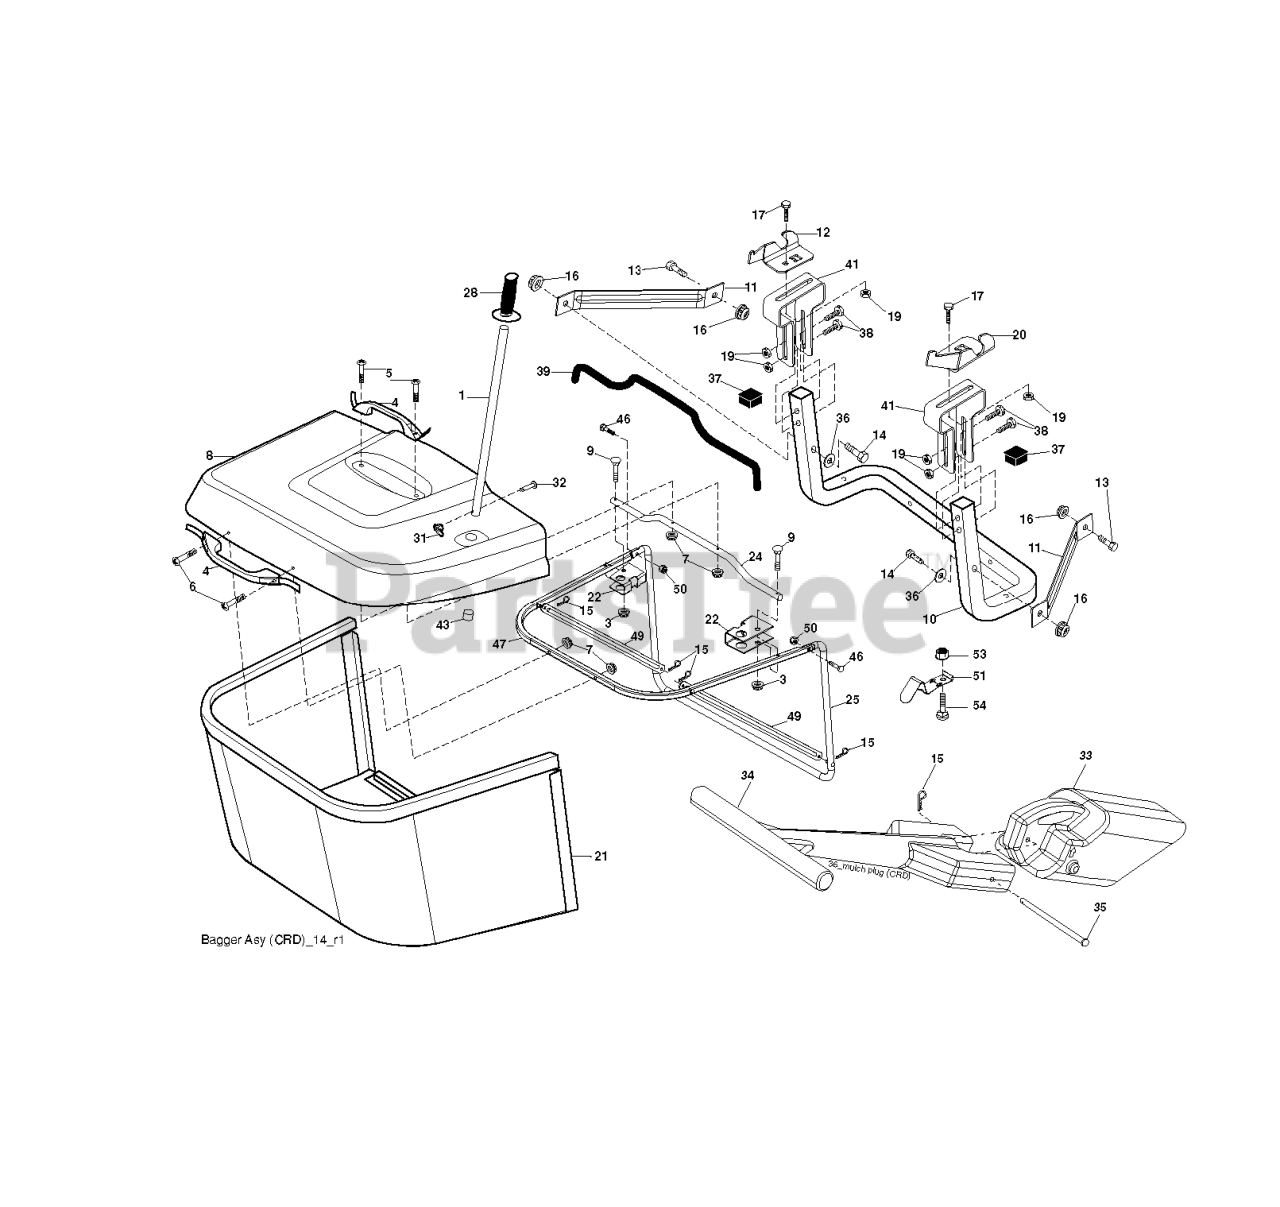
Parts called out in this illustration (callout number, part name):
1	TUBE HANDLE
3	NUT T
4	HANDLE.BAGGER.W/LVRS.BLK.CRD
5	SCREW.PAN.HEAD
6	REPL BY 532 75 00-29
8	COVER.PNT.BGR.CRD.WSLOTS.MS668
9	Bolt Carriage 1/4-20 x 2.25d x Gr.5
10	TUBE
11	BRACKET.SUPPORT.UPPER.BAG.CRD
12	BRKT PIVOT
14	BOLT-HEX EAK
15	RETAINER-SPRNG RB
16	NUT LOCK FLG 3/8-16 UNC
17	RP BOLT 5/16-18 X3/4 ZN/YEL GR
19	NUT LOCK HEX FLANGE 5/16-18
20	BRKT.PIVOT.RH.CRD
21	BAGGER.ASM.CRD.2007
22	BRKT.SIDE.BAG.CRD
24	TUBE.PIVOT.BAG.CRD.BLACK
25	PIPE
28	GRIP.HANDLE.BLACK
31	RETAINER CLIP
32	RIVET,DRILLED
33	MULCH PLUG, CTH150
34	HANDLE.MULCHER.92.CRD (2 2)
36	WASHER
37	Plug Support Bagger CRD
38	BOLT.5/16-18X2.5
39	SEAL.BAGGER.CRD
41	BRKT.VERT.ADJ.BAGGER.CRD
43	PLUG, TUBING END
46	BOLT.CARRIAGE.5/16-18
47	PIPE
49	ROD
50	NUT.71038.31-18.HEX.NYLOCK
51	LATCH
53	NUT
54	BOLT
